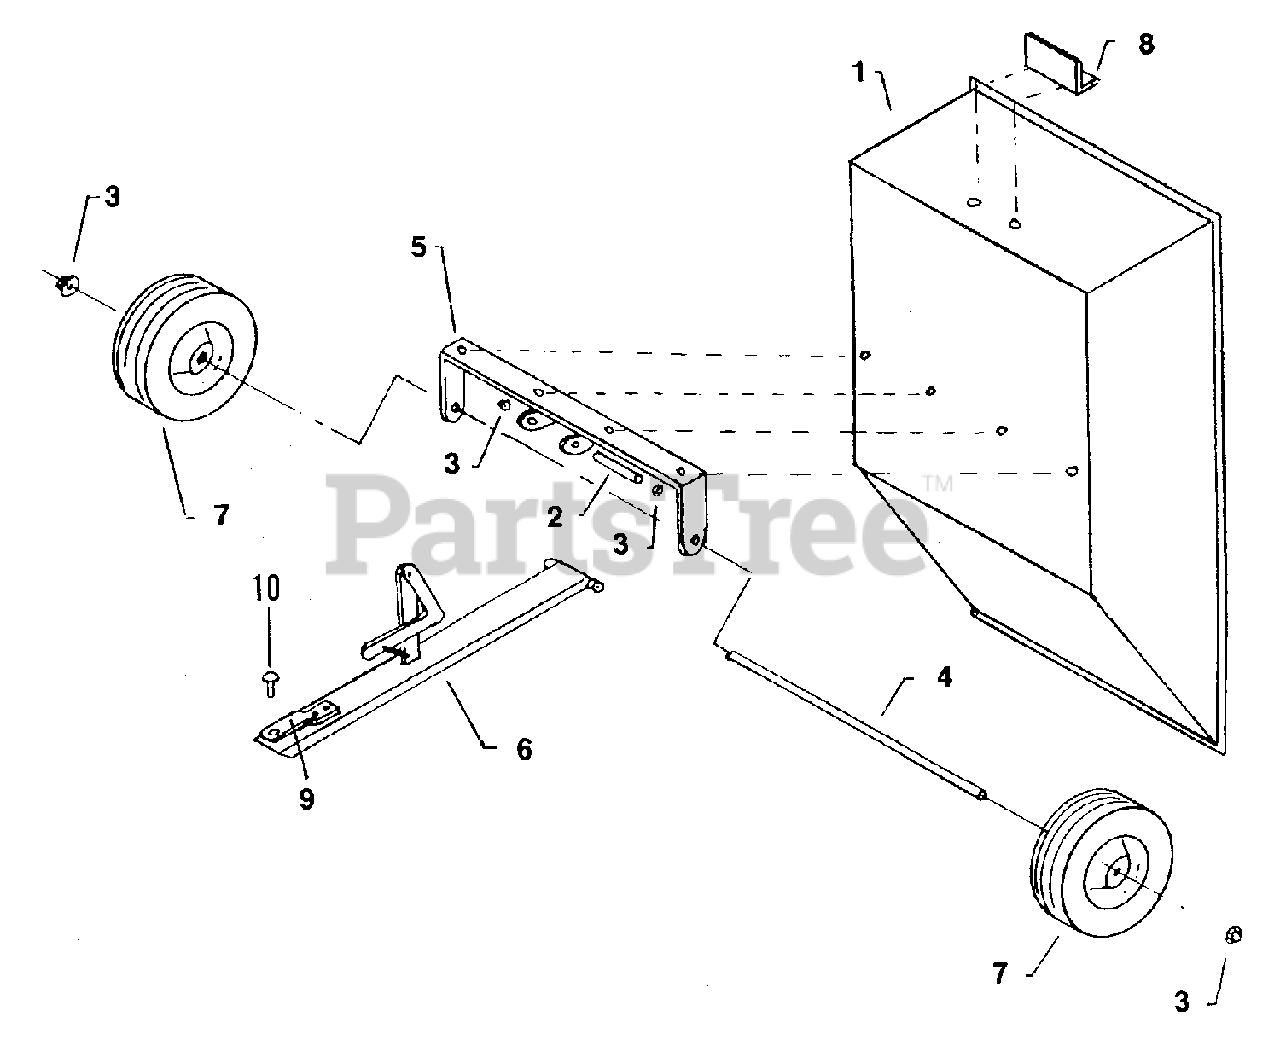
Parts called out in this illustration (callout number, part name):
3	DRIVE CAP
5	AXLE SUPPORT
7	WHEEL W/TIRE
8	LATCH HOLDER
9	CLEVIS BAR
